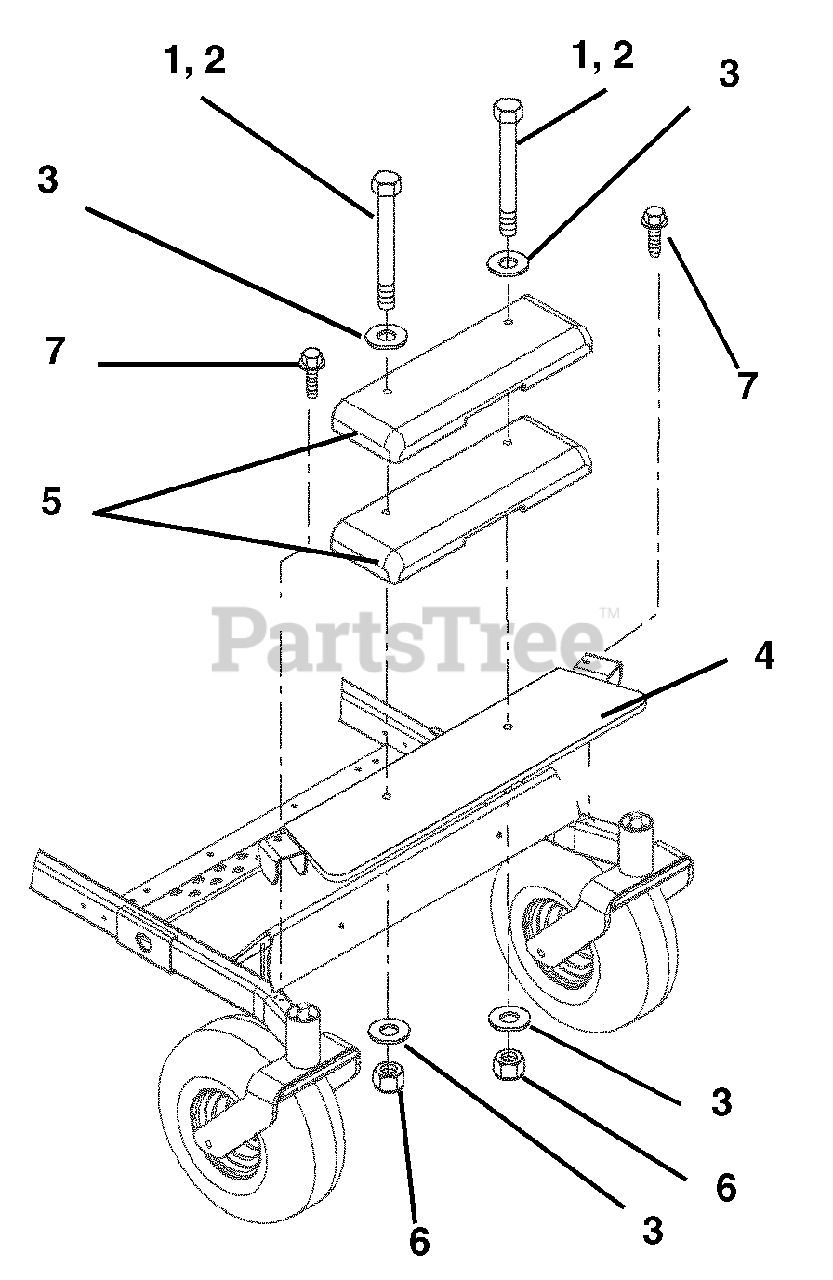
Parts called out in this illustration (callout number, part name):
1	@BLT-HEX .50-13X7.50 GR5 YWZC
2	@BLT-HEX .50-13X5.50 GR5YWZC
3	WSHR-FL-STL .505X1.00X.062YWZC
4	WMT, WEIGHT KIT MTG.-BLACK
5	WEIGHT-REAR FRAME
6	@NUT-LK-CTR .50-13 YWZC
7	@SCR-TAP .38-16X.75 HWH TR YWZ
